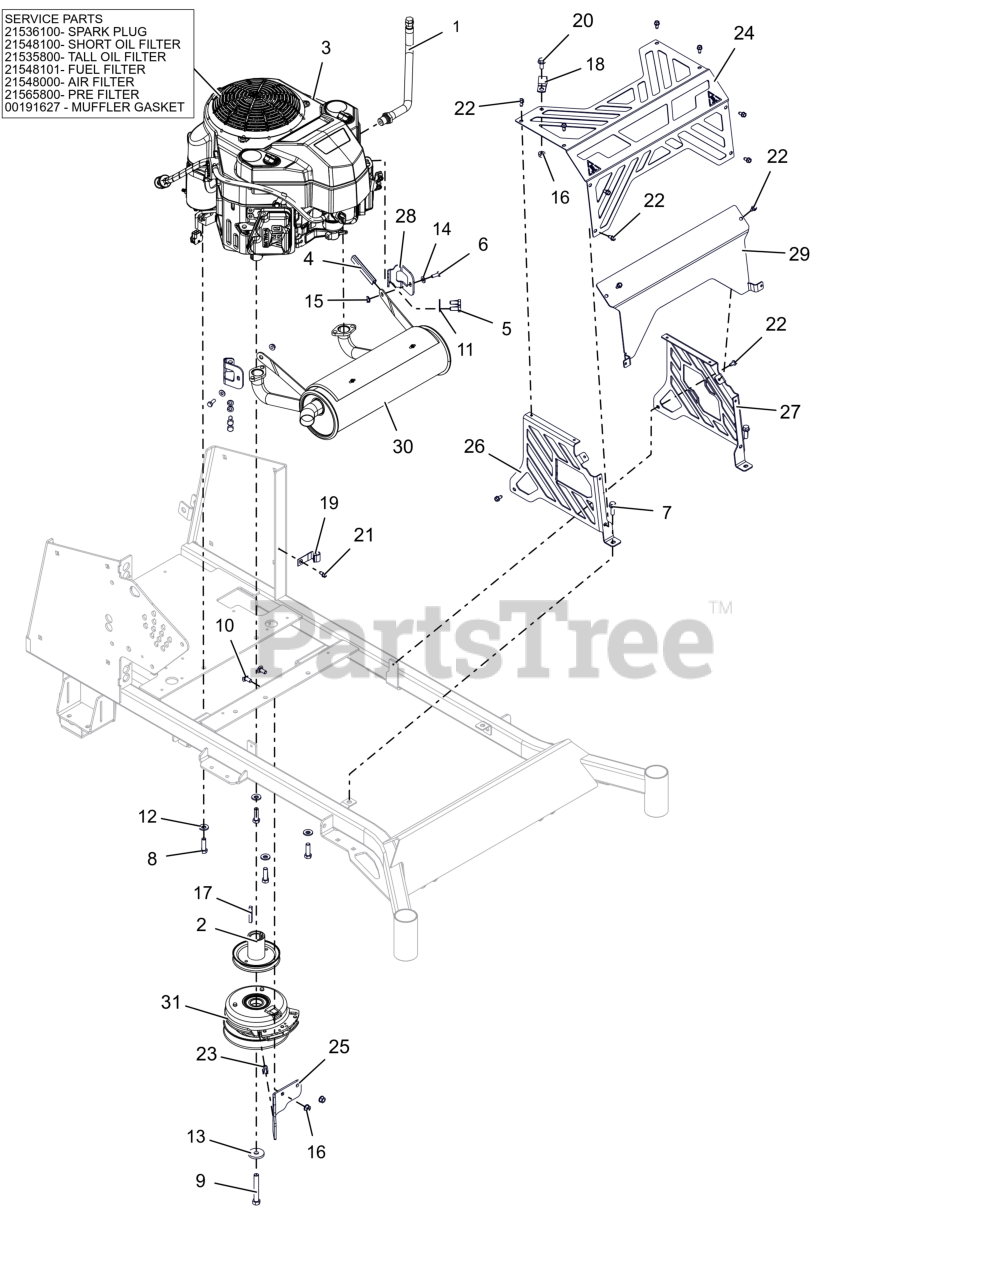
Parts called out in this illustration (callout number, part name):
1	HOSE, OIL DRAIN
2	SHEAVE, ENGINE 4.50 X 1.127
3	ENGINE, KAWASAKI FS651V
4	STRIP, COWL
5	BLT, HEX M8-1.25X20 G8.8 ZCC
6	BLT, HEX .25-20X.75 G5 ZCC
7	BLT- HEX-FLG .31-18X1.00 ZB500
8	BLT, HEX .38-16X1.25 G5 ZCC NT
9	BLT, HEX .44-20X3.00 G8 ZCC NT
10	BLT, RHSSN.31-18X.750 G5 ZCC
11	WSHR,LK-REG .312X.078 ZCC
12	WASHER, 3/8" SPRING DISC
13	WASHER, 7/16" SPRING DISK
14	WSHR,FLT .281X.625X.065 ZCC
15	NUT-LK-CTR-FLG .25-20 ZC120
16	NUT,LK-CTR-FLG .31-18 GF ZCC
17	KEY-STR .25X1.75X.25
18	CLAMP, CUSHIONED STEEL .75
19	J-CLAMP
20	BLT- SERHFWH .312-18X.75 ZCC
21	SCR-TAP .25-20X.50 HWH ZCC
22	SCR-TAP .25X.50 HWH ZB500
23	BSHG, CLUTCH
24	PANEL- MFLR GUARD-FRONT
25	BRKT- CLUTCH STOP
26	GUARD- MUFFLER (RH)
27	PANEL- MFLR GUARD-LS
28	BRKT- MUFFLER MOUNT
29	BAFFLE, MFLR GUARD (BLACK)
30	EXHAUST, KAWASAKI PROSTANCE
31	CLUTCH- WARNER
